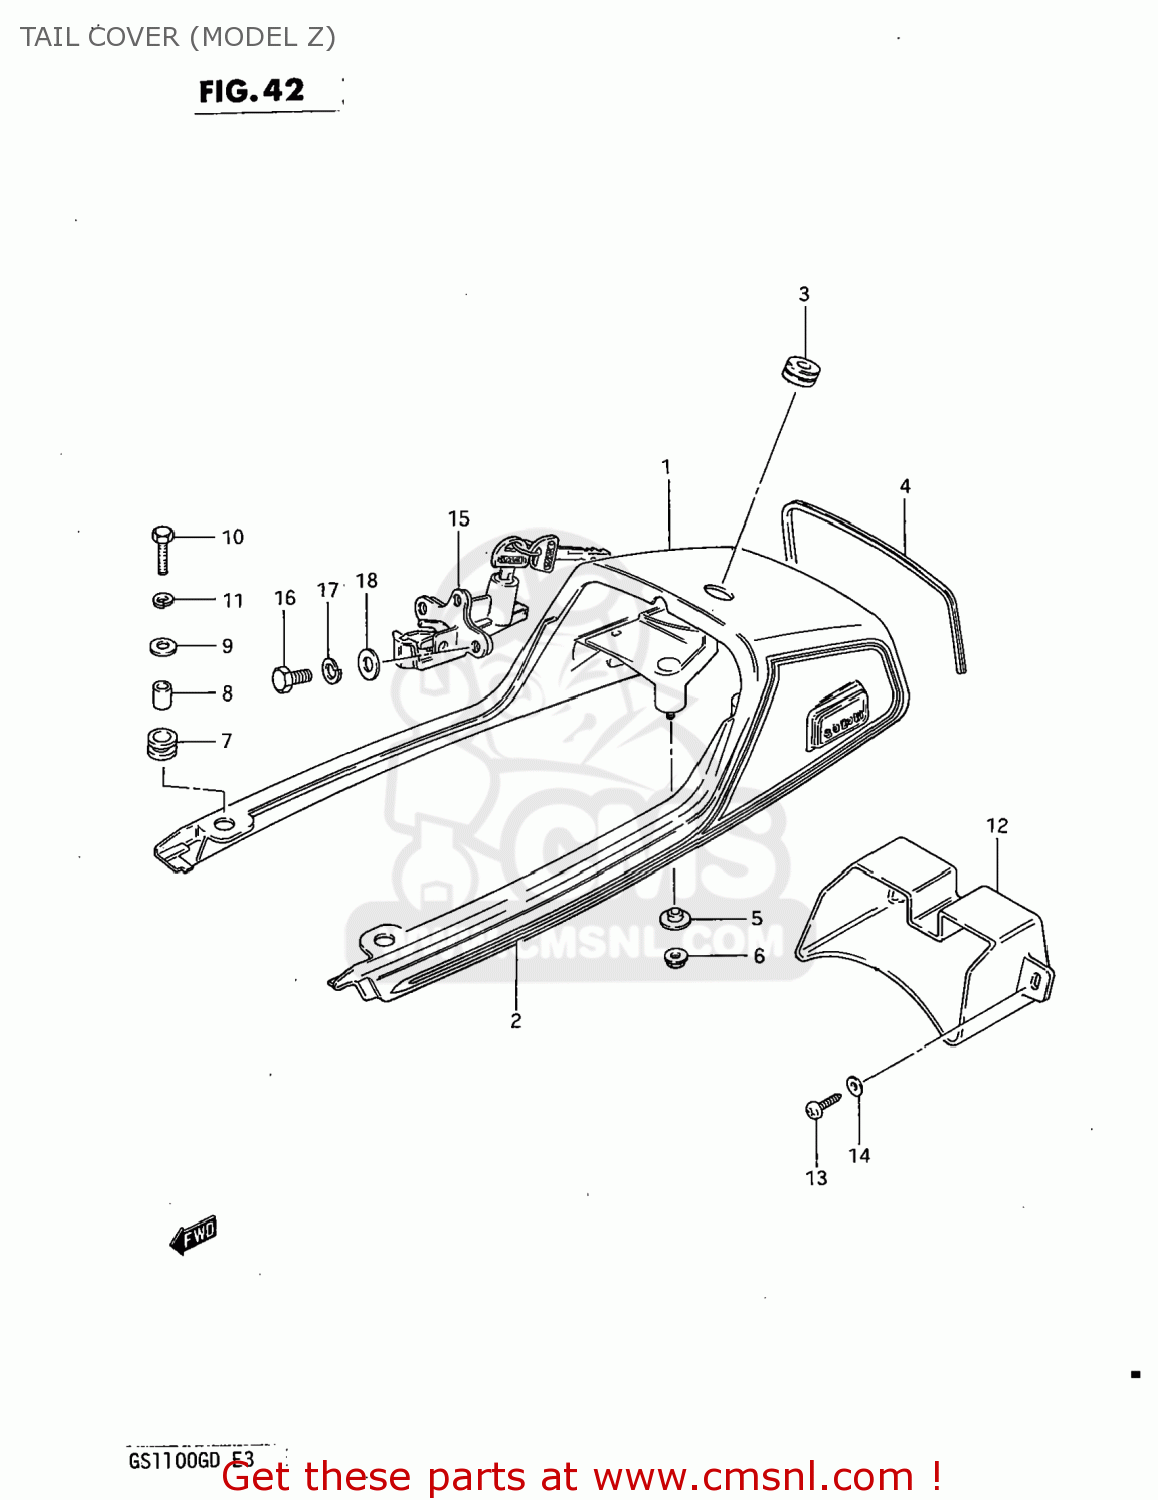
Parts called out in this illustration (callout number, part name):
1	COVER SET,SEAT TAIL
2	TAPE SET,SEAT TAIL COVER
3	GROMMET,SEAT LOCK HOLE
4	MOLDING,SEAT TAIL COVER
5	WASHER
6	NUT 6MM
7	CUSHION
8	SPACER (7X10X12)
9	WASHER (6.5X24X1.6)
10	BOLT
11	LOCK WASHER
12	BOX, SEAT TAIL
13	SCREW
14	LOCK WASHER
15	LOCK SET,SEAT
16	BOLT
17	LOCK WASHER
18	WASHER
